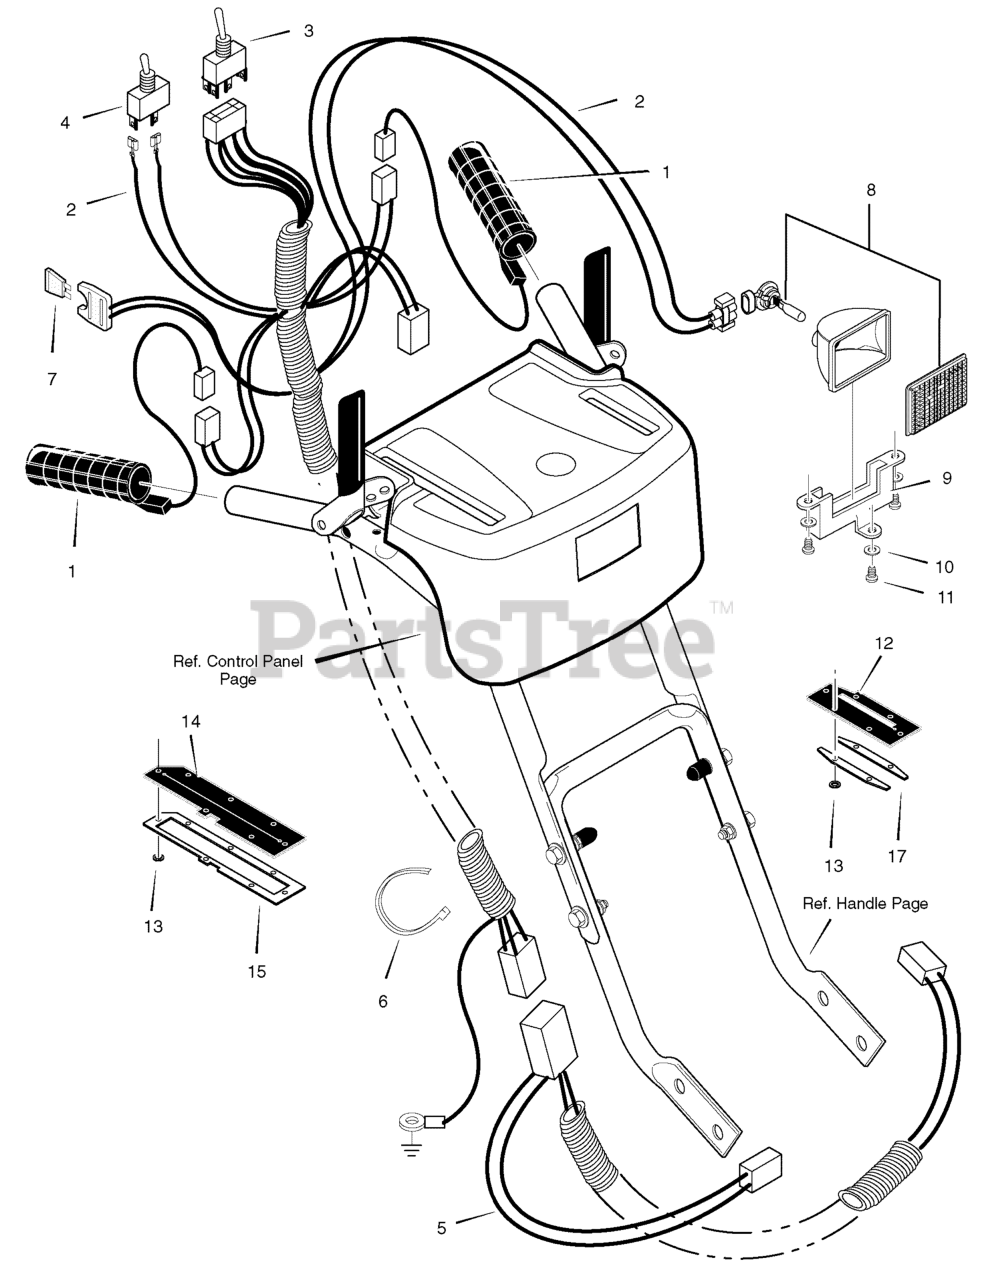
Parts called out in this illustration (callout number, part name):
1	GRIP, HEATED
2	WIRE HARNESS, UPPER
3	SWITCH, CHUTE ROTATION
4	SWITCH, HEATED GRIP
5	WIRE HARNESS, LOWER
6	TIE, CABLE
7	FUSE, 7.5 AMP AUTOMOTIVE
8	HEADLIGHT ASSEMBLY *
10	WASHER, FLAT
11	SCREW #8 X .50
12	COVER, CHUTE LEVER
13	NUT, PUSH
14	COVER, SPEED LEVER
15	FRAME, SPEED LEVER
17	FRAME, CHUTE LEVER
